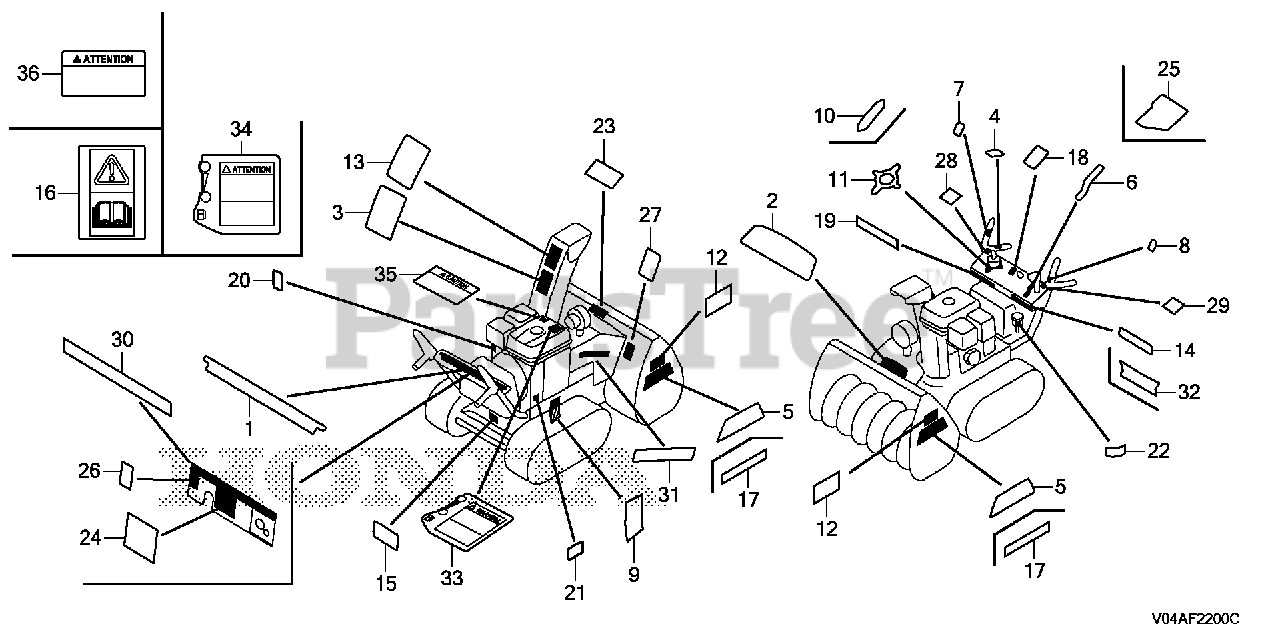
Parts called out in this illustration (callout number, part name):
1	LABEL, OPERATION (C)(ENGLISH)
3	LABEL, WARNING (ENGLISH)
5	MARK, EMBLEM
6	MARK, CHANGE INDICATION
7	MARK, AUGER CLUTCH (ENGLISH)
8	MARK, CLUTCH (ENGLISH)
9	MARK, HEIGHT ADJUSTING
10	MARK, CHUTE CONTROL OPERATION (ENGLISH)
12	MARK, HOUSING DANGER (ENGLISH)
13	MARK, DISCHARGE DANGER (ENGLISH)
14	MARK (H.S.T.)
15	MARK, INDICATION (H.S.T.)(ENGLISH)
18	MARK, THROTTLE (ENGLISH)
19	MARK B, HONDA
20	MARK, FUEL INDICATION (ENGLISH)
21	MARK, OIL CAUTION (ENGLISH)
22	LABEL, OIL RECOMMENDATION (ENGLISH)
